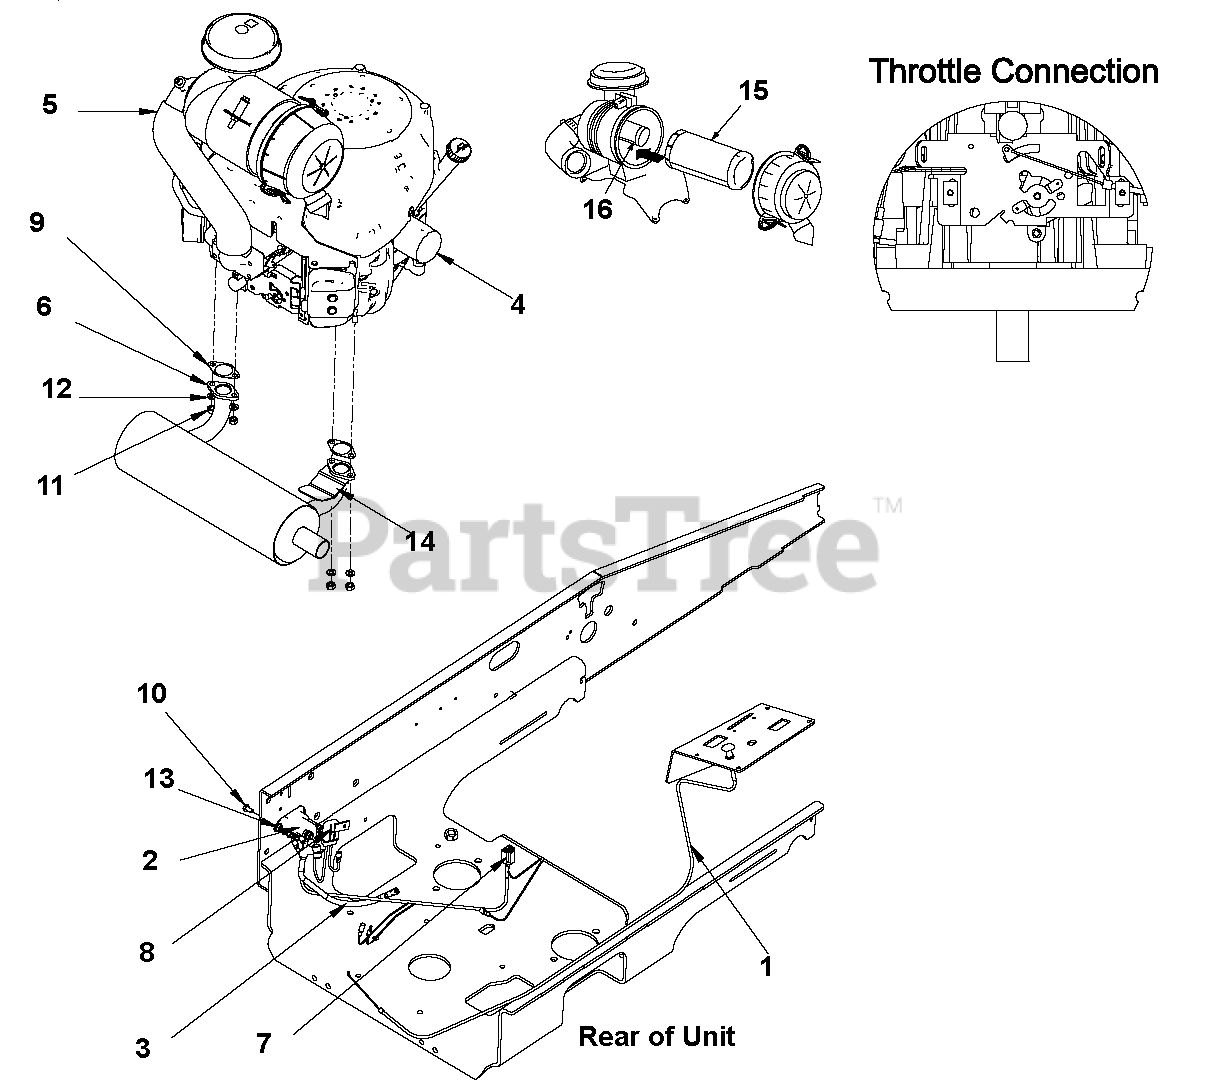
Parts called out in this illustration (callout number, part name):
1	Cable, Choke 48"
2	Solenoid, 12 V Starter
3	Cable, 12’ Starter
4	Oil Filter
5	Engine, Kawasaki 19 HP (402)
6	Muffler, Kawasaki ONLY FH-HORI (400)
7	Adapter Harness, Kawasaki
8	Adapter Harness, Kawasaki, Fuse
9	Kit, Muffler Gasket (Includes items 9, 11 and 12)
10	Bolt, 1/4-20 x .500 Hex 5
11	Nut, M8 x 1.25 Hex GR8.8
12	Washer, M8 Spring Lock
13	Locknut, 1/4-20 Whiz
14	Shield, Exhaust
15	Filter, Primary Air (400)
16	Filter, Secondary Air (400)
